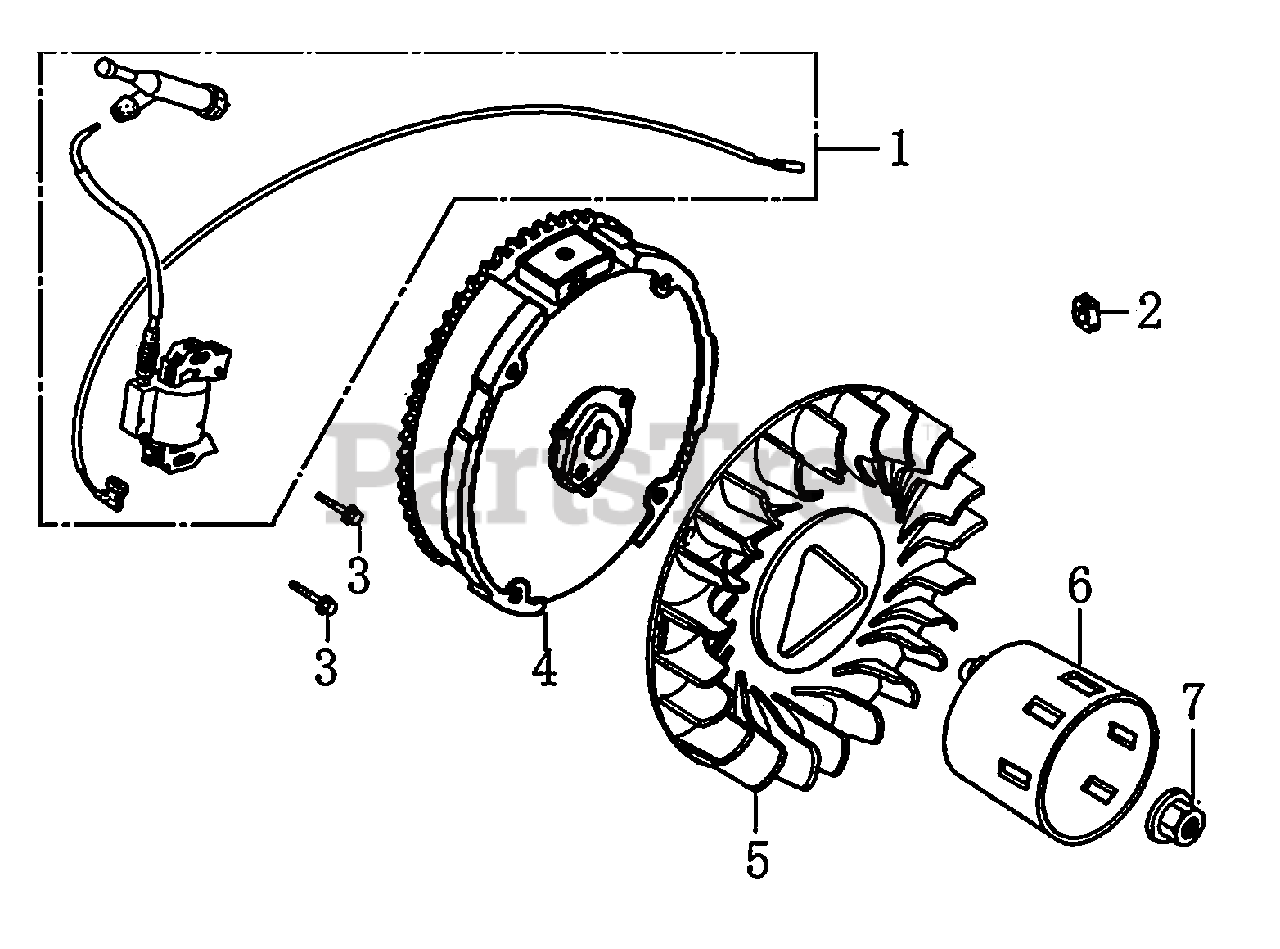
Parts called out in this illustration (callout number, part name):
1	COIL ASSY., IGNITION
2	GROMMET, CORD
3	BOLT, FLANGE, M6X25
5	FAN, COOLING
6	PULLEY, STARTER
7	NUT SPECIAL, 16MM
